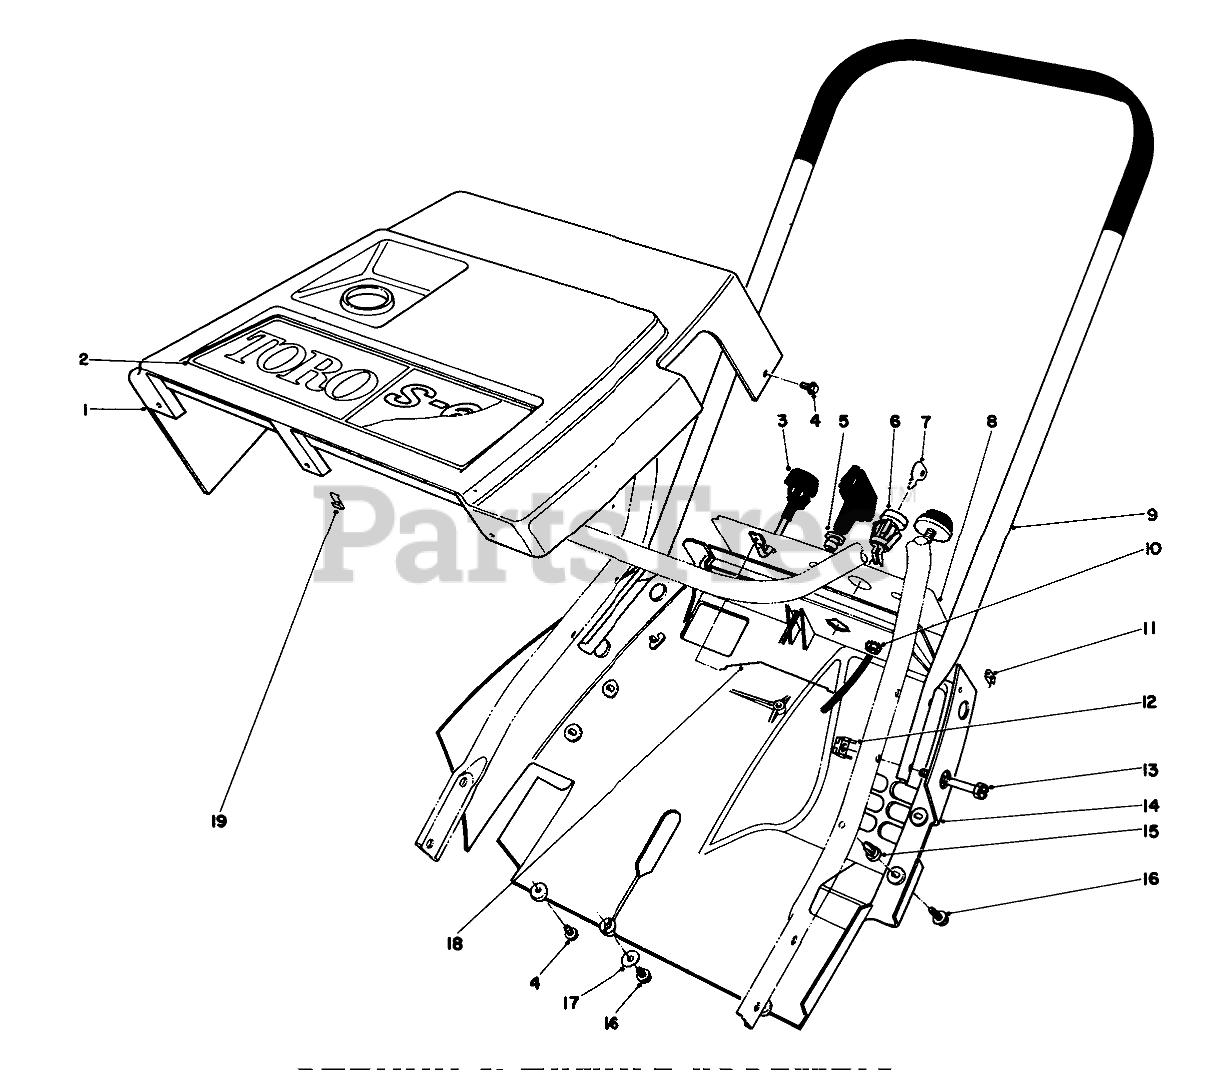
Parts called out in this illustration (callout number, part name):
1	Shroud-Upper
2	TORO DECAL
3	CHOKE CONTROL ASM
4	SCREW-HWHTF
5	GUIDE-ROPE, STARTER
6	SWITCH
7	Key
8	Decal-Control Panel
9	Handle-Upper
10	NUT-KEPS
12	TINNERMAN NUT
13	SCREW-HEX HD SLOT
14	LOWER SHROUD
15	Nut-Push
16	SCREW-HWHTF
17	WASHER-FLAT
18	CONTROL WIRE
19	NUT "U"
